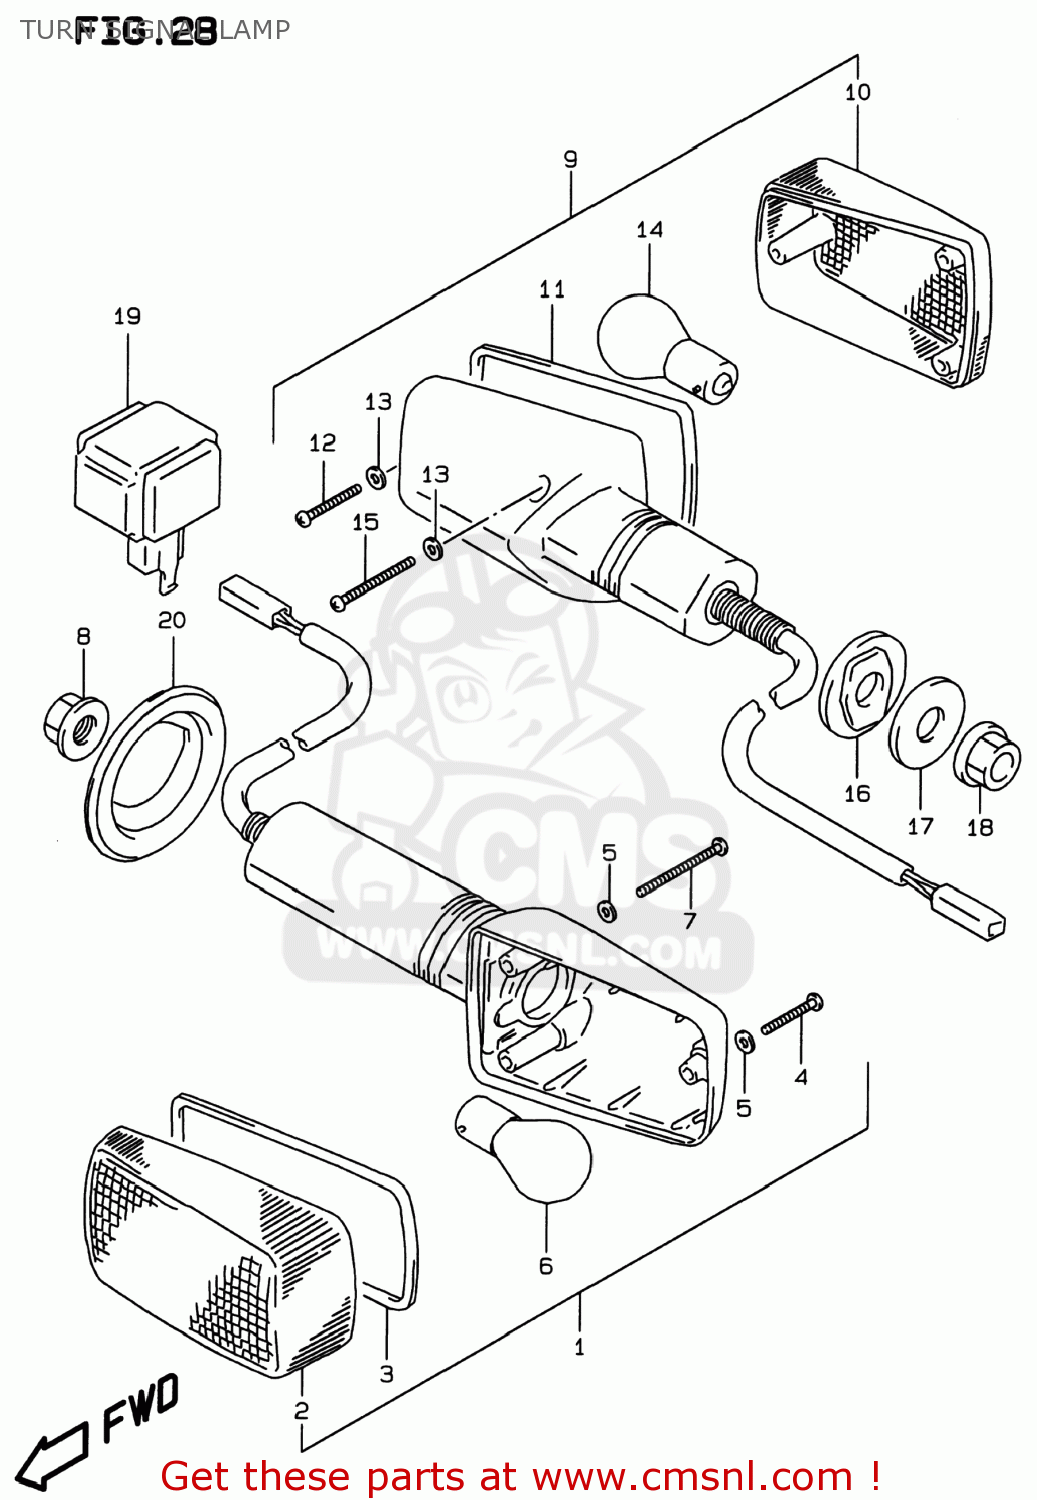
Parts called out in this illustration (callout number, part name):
1	LAMP ASSY,FR TURN SIGNAL
2	LENS
3	GASKET (NAS)
4	SCREW
5	GASKET (NAS)
6	BULB(12V21W)
7	SCREW(3X30)
8	NUT
9	LAMP ASSY,RR TURNSIGNAL
10	LENS
11	GASKET (NAS)
12	SCREW
13	GASKET (NAS)
14	BULB(12V21W)
15	SCREW(3X30)
16	SPACER,RR TURNSIGNAL
17	WASHER(10.5X30X2.3)
18	NUT
19	RELAY ASSY
20	GROMMET
